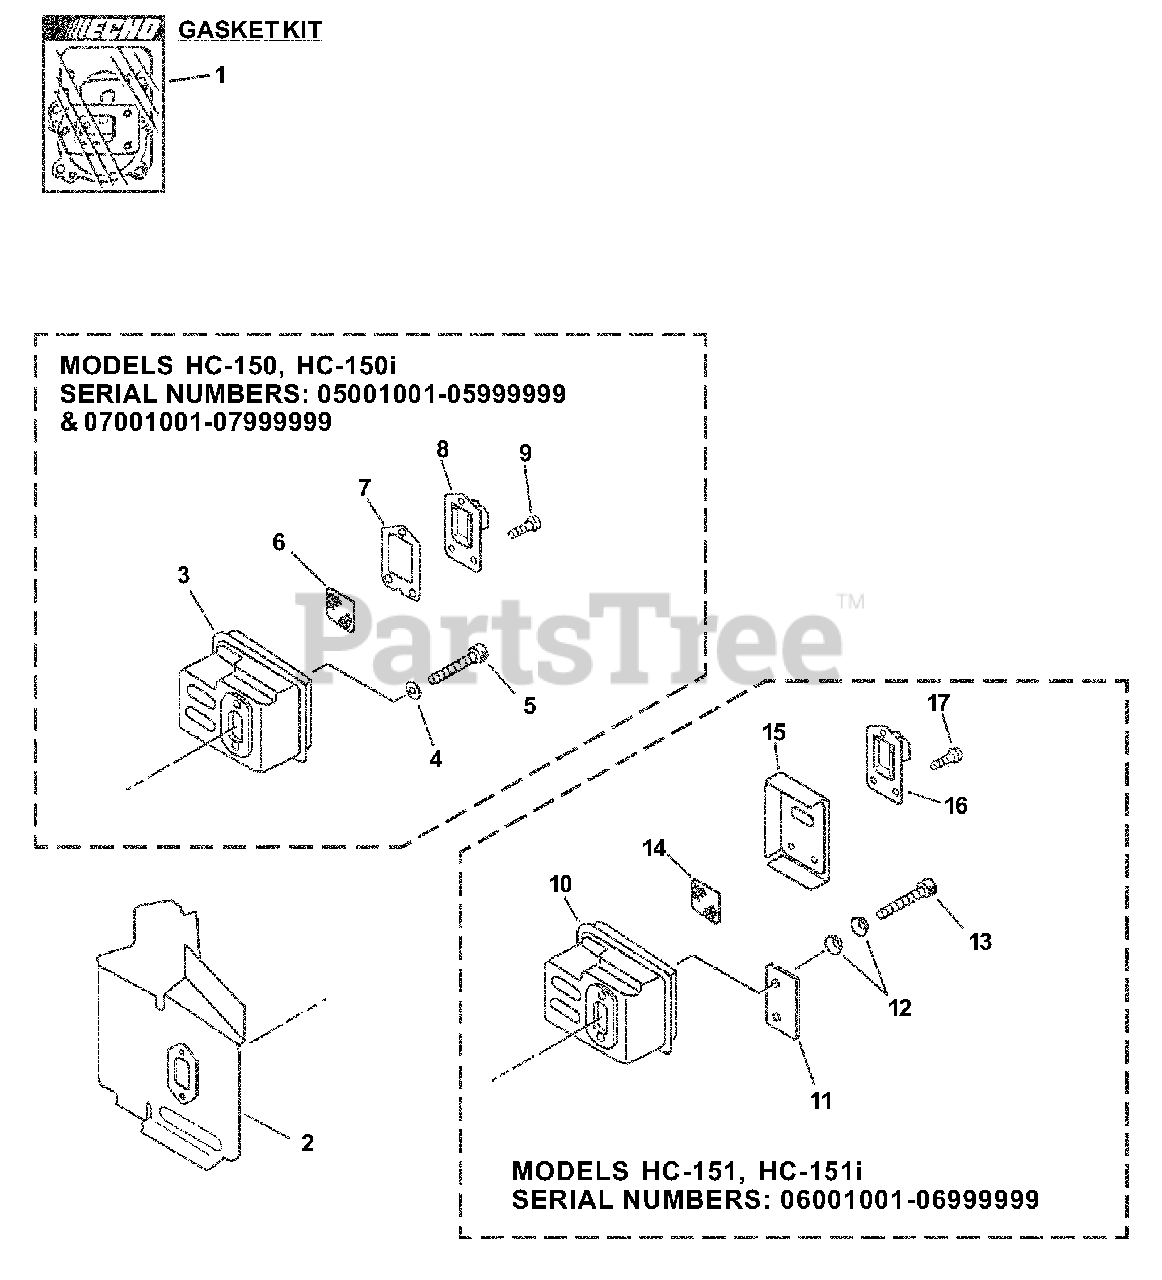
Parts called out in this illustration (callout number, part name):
1	GASKET KIT
2	HEAT SHIELD, EXHAUST
4	WASHER, FLAT 5.5×10×0.8
5	BOLT M5×50
6	SCREEN, SPARK ARRESTER
7	GASKET, EXHAUST
8	GUIDE, EXHAUST
9	SCREW 4×10
10	MUFFLER
11	PLATE, EYE
12	CONICAL WASHER
13	BOLT 5×55
14	SCREEN, SPARK ARRESTER
15	GASKET, EXHAUST
16	GUIDE, EXHAUST
17	SCREW 4×12
